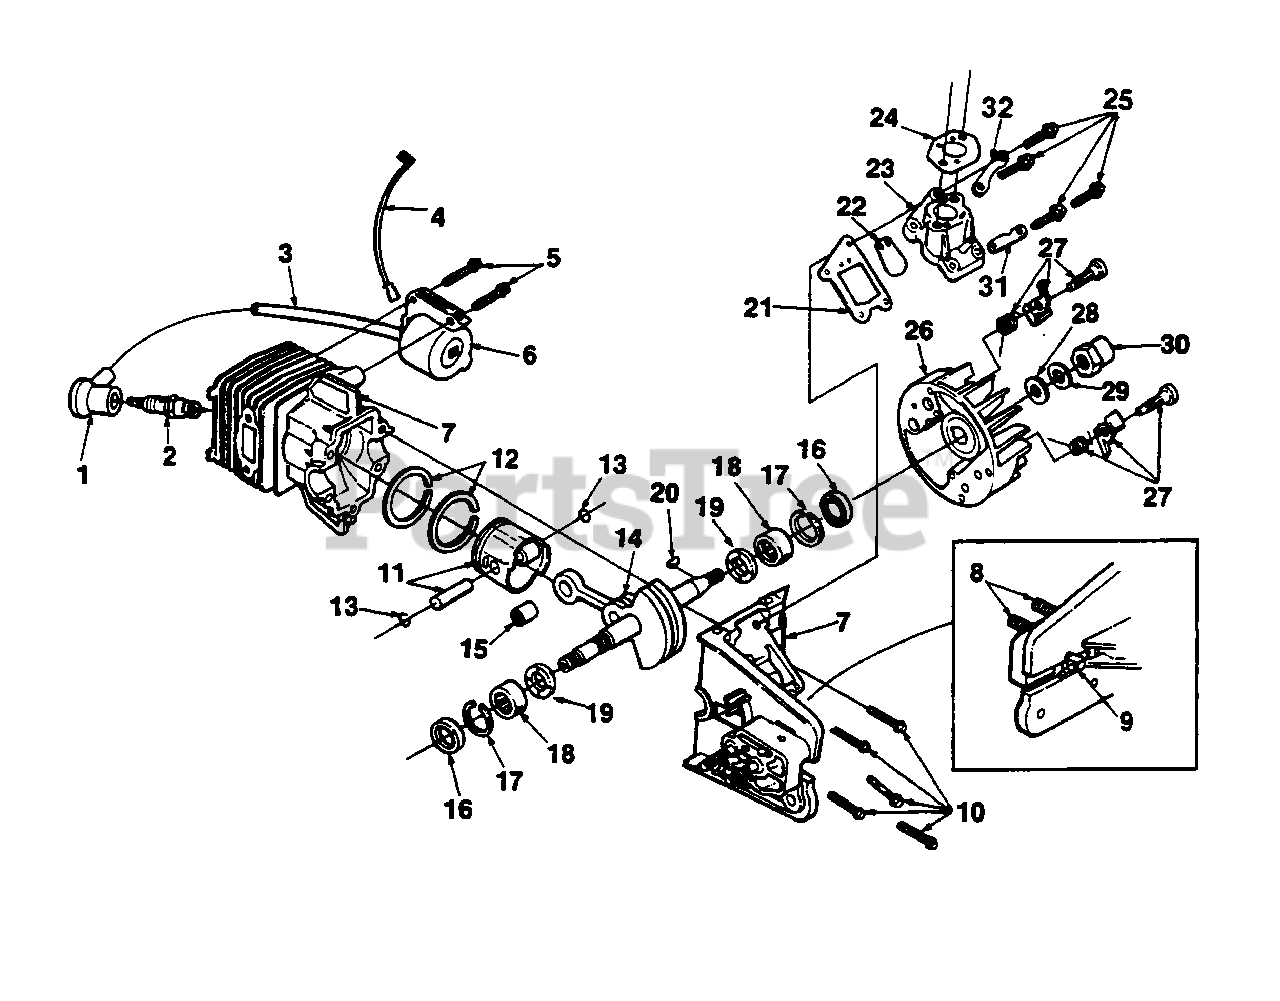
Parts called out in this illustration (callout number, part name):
1	TERMINAL- High tension lead
2	SPARK PLUG (DJ-7Y)
3	LEAD- High tension
4	LEAD- Ground
5	SCREW- Mach., hex hd. 8-32 x 7/8
6	MODULE- Ignition
7	CRANKCASE & CYLINDER
8	BOLT- Guide bar
9	FITTING
10	SCREW- 10-24 x 1 1/8
11	PISTON & PIN
12	PISTON RINGS
13	RING- Retaining
14	CRANKSHAFT
15	BEARING- Needle
16	SEAL- Shaft
17	RING- Retaining
18	BEARING- Needle
19	BEARING- Thrust
20	KEY- Magneto
21	GASKET- Manifold
22	REED
23	MANIFOLD- Intake
24	GASKET- Carburetor
25	SCREW- Hex washer 8-32 x 5/8
26	ROTOR- Magneto
27	PAWL- Starter
28	WASHER- Flat 5/16
29	WASHER- Lock 5/16
30	NUT- Guide
31	WASHER- Intake manifold
32	WASHER- Intake manifold
